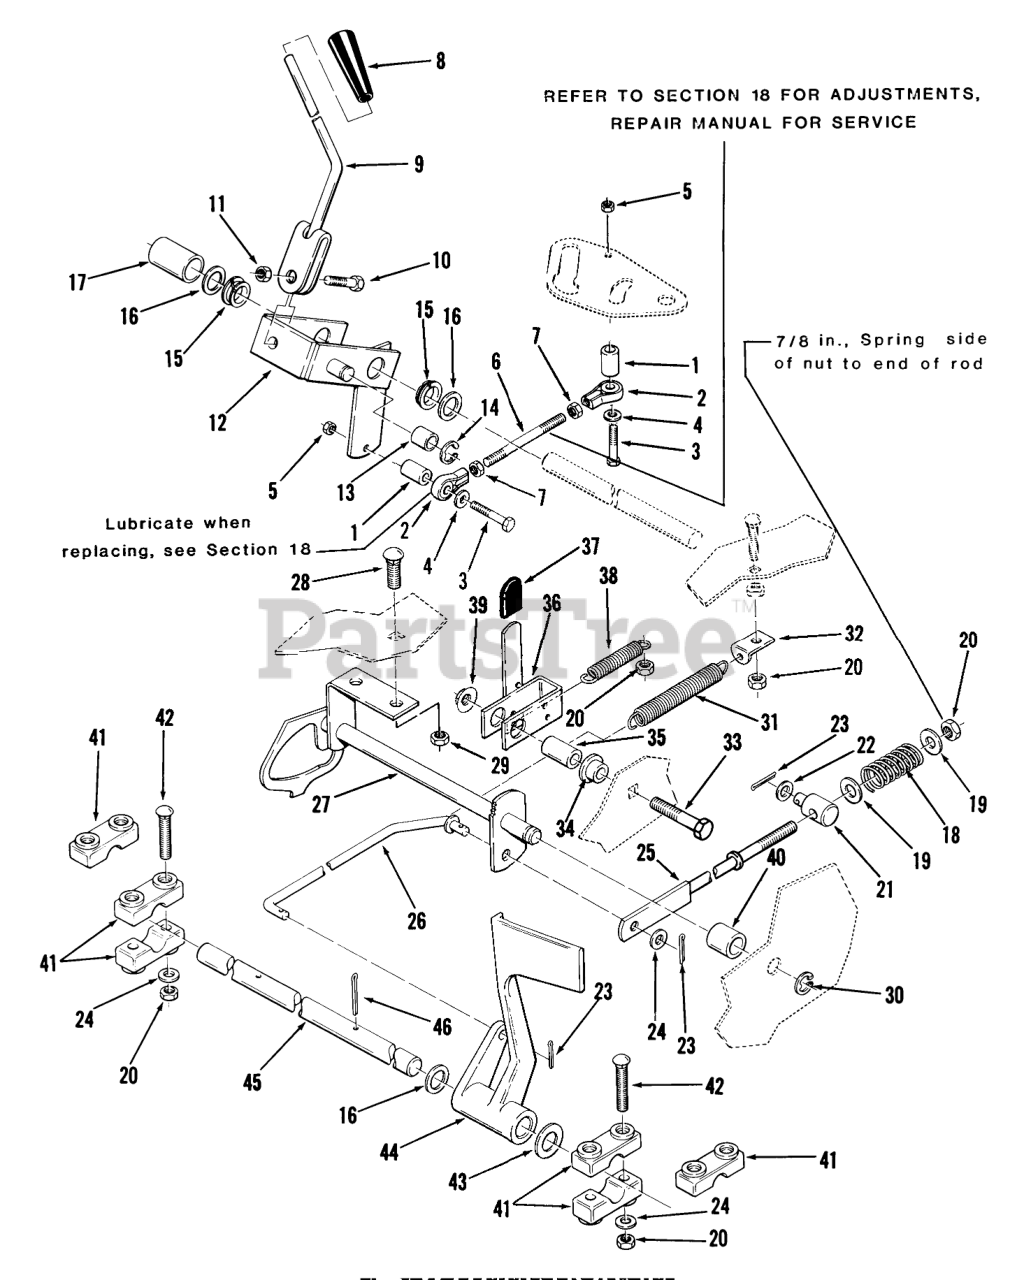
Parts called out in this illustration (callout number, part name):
1	Spacer
2	ASSY ROD END
3	Bolt 1/4-20 X 1 1/2
5	Nut
6	Control Rod
7	Jam Nut 1/4-28
8	KNOB
9	CONTROL ARM ASSY
10	Bolt
11	NUT
12	Control Cam
13	BEARING-CAM RETURN
14	E Ring
15	Bushing
16	Washer
17	SPACER
18	SPRING FRICTION
19	Collar
20	Nut
21	TRUNNION-LIFT
22	Washer
23	Cotter Pin
24	WASHER 5/16 SAE
25	REAR BRAKE ROD ASM R
26	BRAKE ROD (FRONT)
27	ASSY NEUTRAL RETU R
28	Carriage Bolt 3/8-16 X 3/4
29	Nut
30	E Ring
31	CLUTCH SPRING
32	CLIP - SPRING
33	Bolt
34	SPACER
35	SPACER
36	Parking Brake Lever
37	GRIP
38	SPRING-EXTENSION
39	LOCKNUT-FLANGE
40	Spacer
41	BLOCK PIVOT
42	Washer
43	Special Washer
44	PEDAL-BRAKE
45	Shaft
